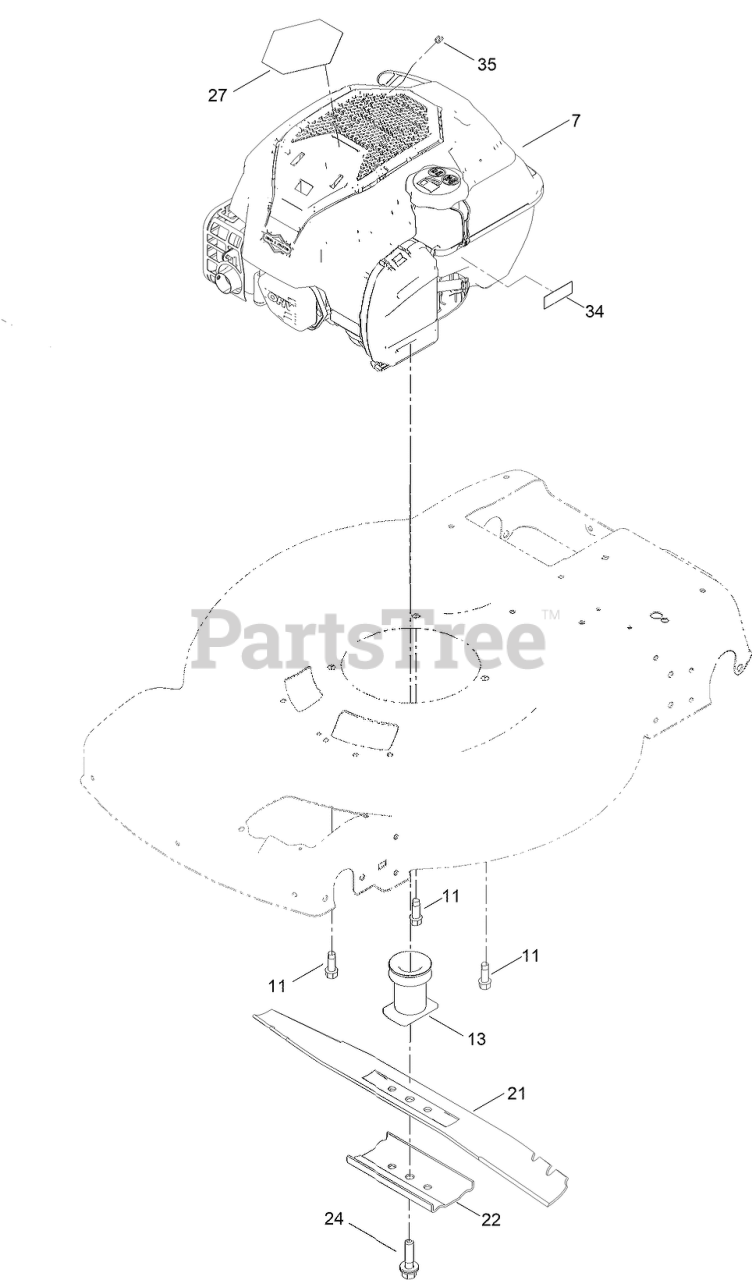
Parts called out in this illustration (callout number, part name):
11	SCREW-THD FORM, HWH
13	DRIVER-BLADE
22	SUPPORT-BLADE
24	BOLT-BLADE
27	DECAL - BRIGGS 675 EXI SS
34	DECAL-LEVEL, FUEL
35	STOP-ROPE
